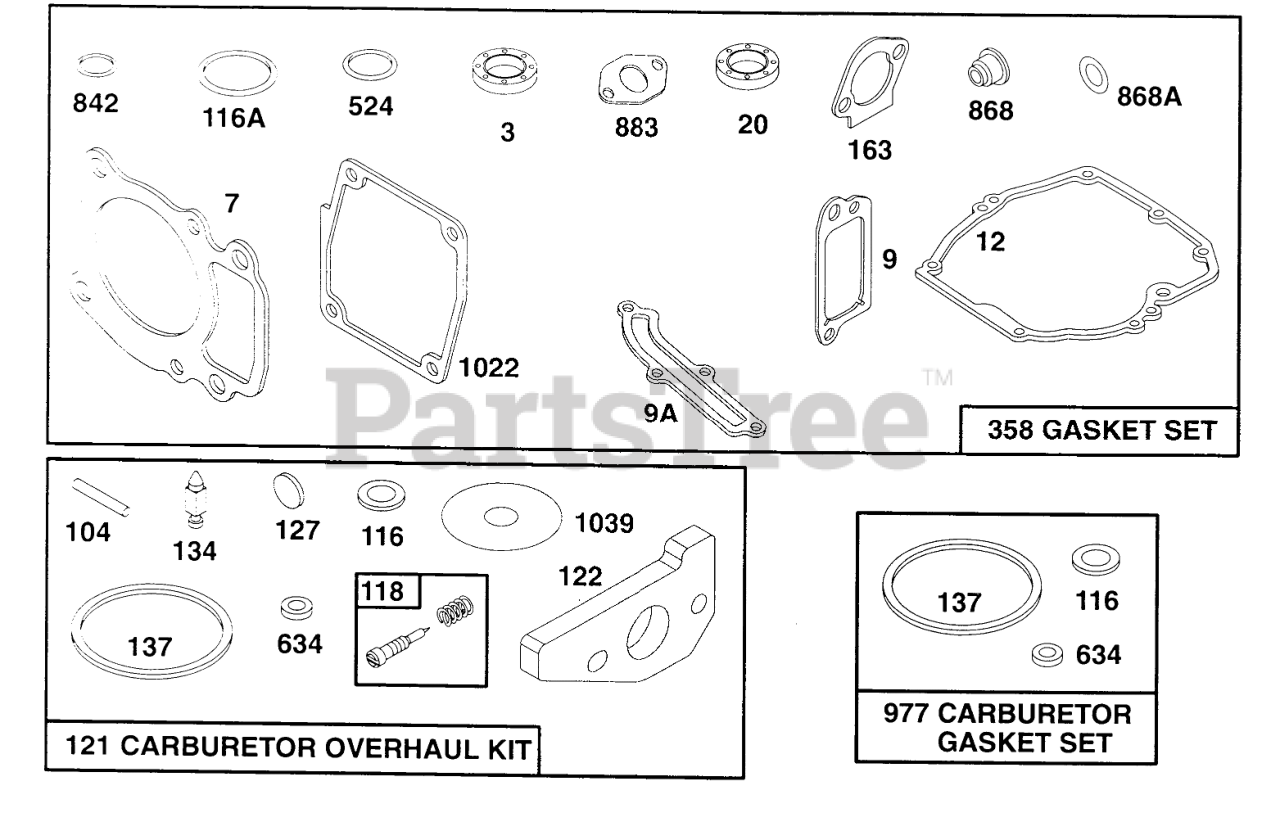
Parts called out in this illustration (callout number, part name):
3	SEAL - OIL
7	CYLINDER HEAD GASKET
9	VALVE - SHUT-OFF
9A	GASKET-BREATHER
12	ENGINE BASE GASKET
20	SEAL-OIL
104	FLOAT HINGE PIN
116	SEALING GASKET
116A	O RING SEAL
118	VALVE KIT - NEEDLE
121	CARBURATOR OVERHAUL KIT
122	ADAPTER ASSEMBLY
127	PLUG
134	Valve-Inlet(Includes Seat)
137	FLOAT BOWL GASKET
163	AIR CLEANER GASKET
358	GASKET SET
524	O-RING
634	SEAL WASHER
842	O-RING
868	SealAssy-Valve
868A	Seal-Valve
883	EXHAUST GASKET
977	CARBURATOR GASKET SET
1022	ROCKER COVER GASKET
1039	FLOAT LIMITER
